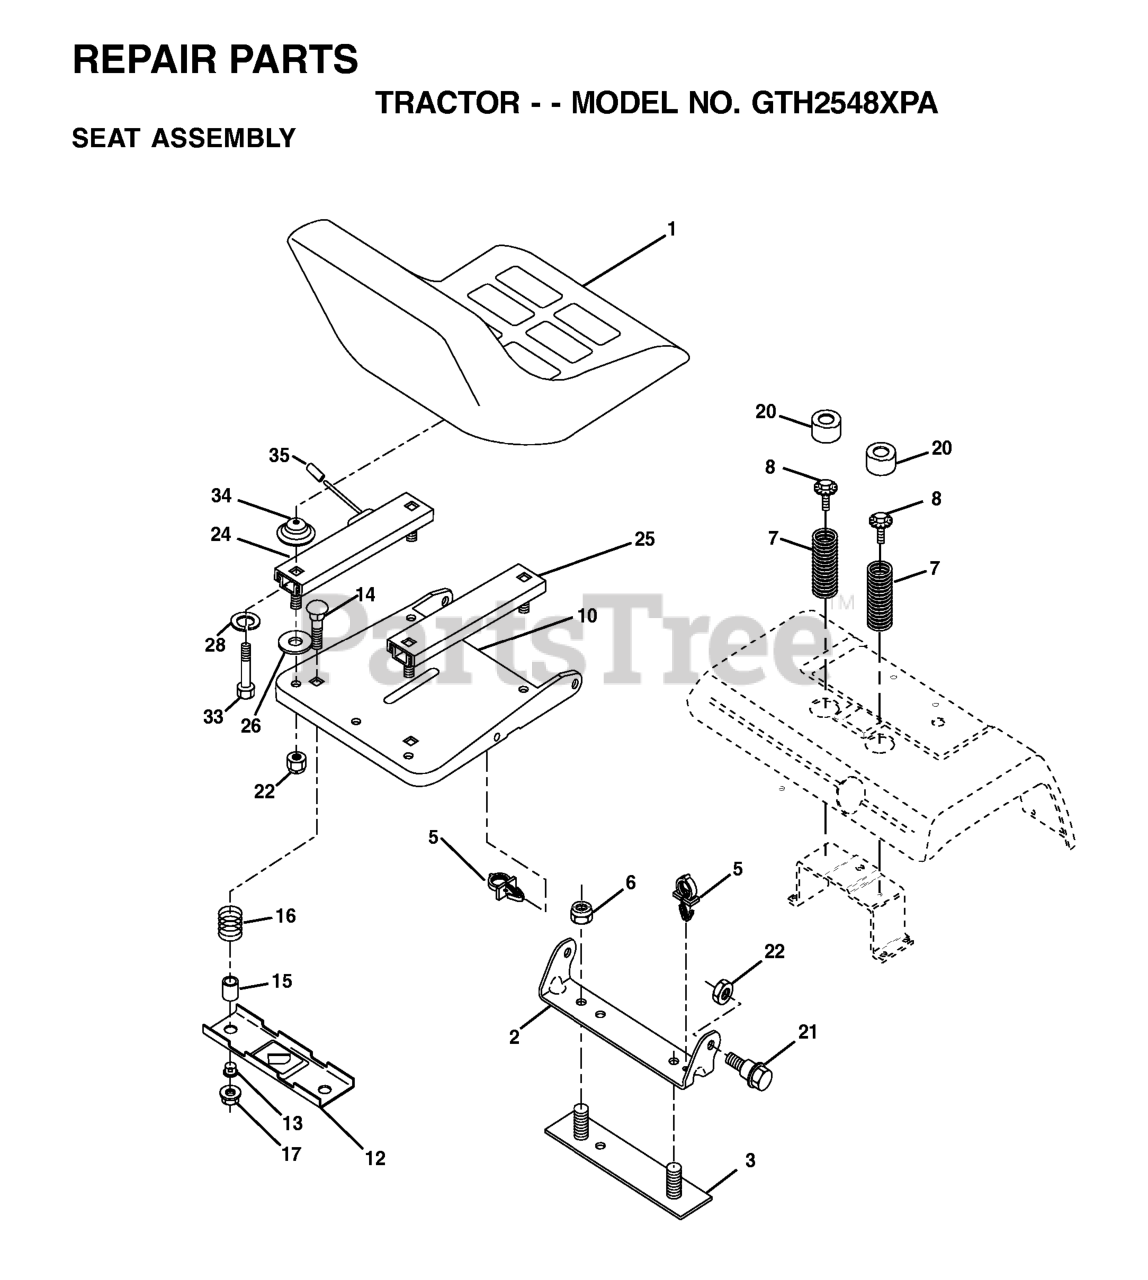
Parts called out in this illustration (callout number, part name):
1	SEAT
2	SEAT PIVOT BRKT
3	STRAP
6	NUT
7	SPRING COMPRESSION
8	BOLT.5/16-18UNCX3/4 W/SEMS.BLK
10	PAN, SEAT
12	BRKT SWITCH
14	BOLT.ROUND.HEAD.SQUARE.NECK
15	SPACER SPLIT
16	SPRING COMPRESSED
17	NUT T
20	CAP SPRING
21	BOLT.SHOULDER.5/16-18
22	NUT.71038.31-18.HEX.NYLOCK
24	TRACK SLIDE, SEAT(L)
25	TRACK SLIDE, SEAT(R)
26	WASHER T
33	BOLT.FIN.HEX.5/16-18UNC X 1.00
35	CAP
